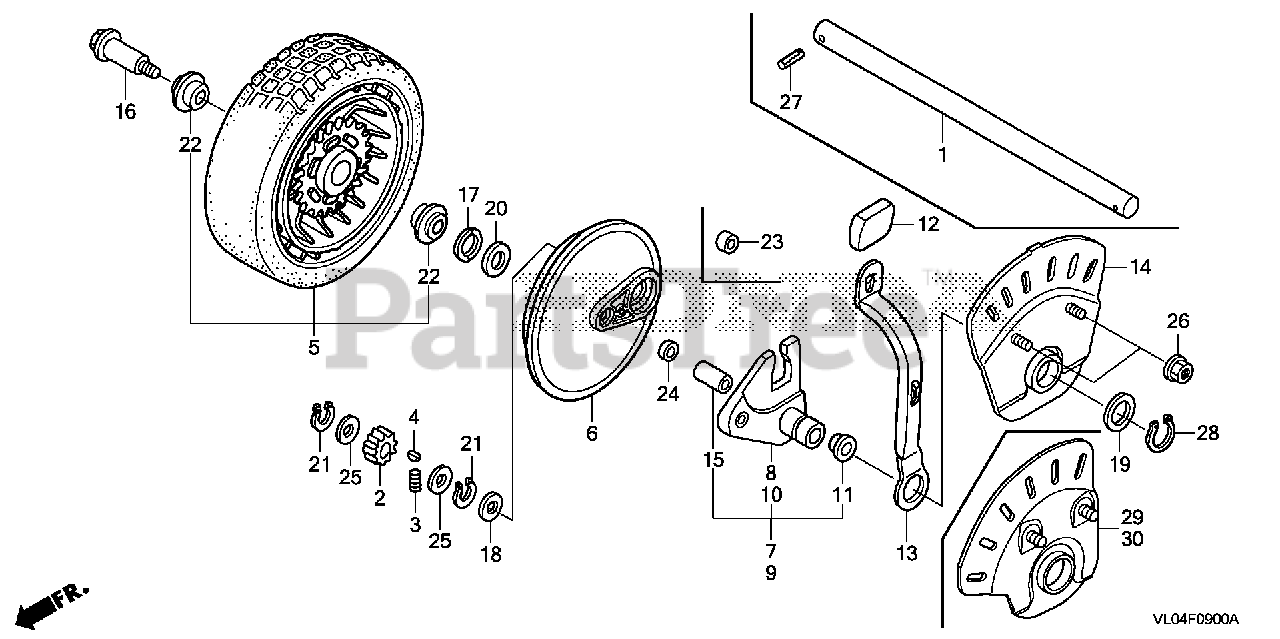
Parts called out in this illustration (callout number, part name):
1	SHAFT, WHEEL
5	WHEEL *NH164* (GRIP GRAY) (RR.)
8	ARM, R. RR. ADJUSTER
10	ARM, L. RR. ADJUSTER
12	GRIP, ADJUSTER *NH164* (GRIP GRAY)
13	PLATE, RR. ADJUSTER
16	BOLT, RR. WHEEL SHAFT
17	WASHER, WHEEL
19	WASHER, FLAT (26X44)
22	BEARING, WHEEL
23	COLLAR, RR. ADJUSTING
26	NUT, FLANGE (8MM)
27	PIN, SPLIT (3.0X25)
27	PIN, SPLIT (3.0X45)
28	CIRCLIP (OUTER) (25MM)
29	PANEL, R. RR. ADJUSTING
30	PANEL, L. RR. ADJUSTING
